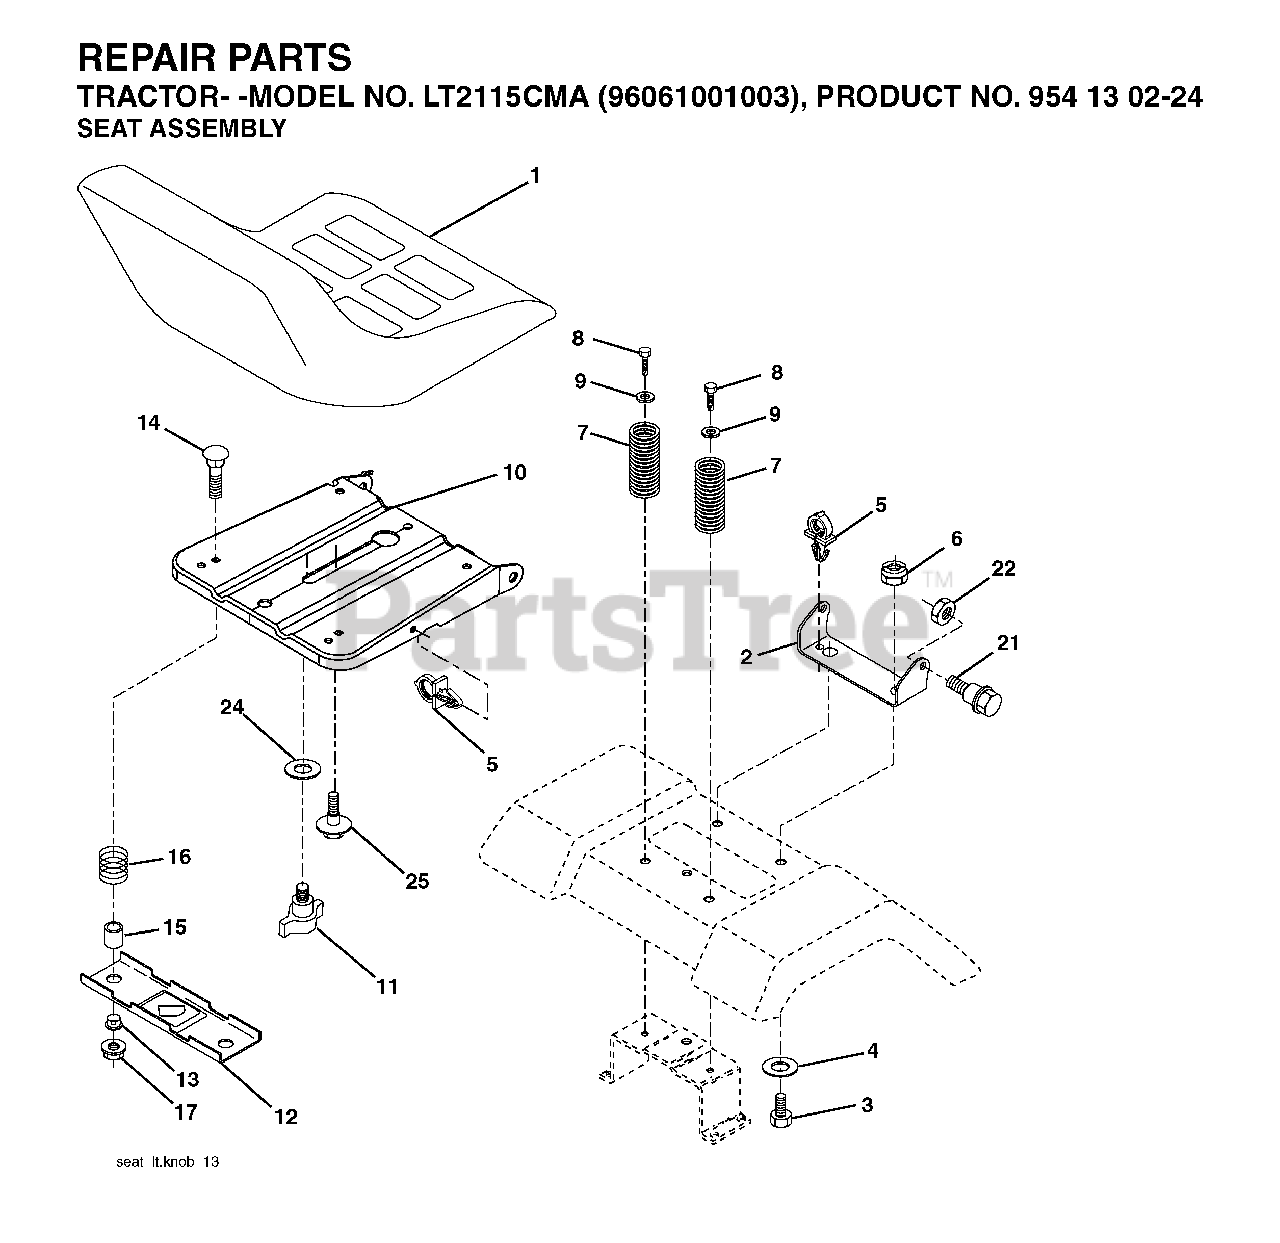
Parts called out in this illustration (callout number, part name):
1	SEAT.XG110.BLK.NO/LOGO
2	SEAT PIVOT BRKT
4	WASHER PM
5	PUSH CLIP
6	NUT
7	SPRING COMPRESSION
8	SCREW 3/8-16X1
9	WASHER
10	AUGR.ASM.30".RH.PNT
11	KNOB.SEAT.ADJ.WINGNUT
12	BRKT SWITCH
14	BOLT.ROUND.HEAD.SQUARE.NECK
15	SPACER SPLIT 28X.96
17	NUT T
21	BOLT.SHOULDER.5/16-18
22	NUT.71038.31-18.HEX.NYLOCK
25	BOLT,SHOULD
